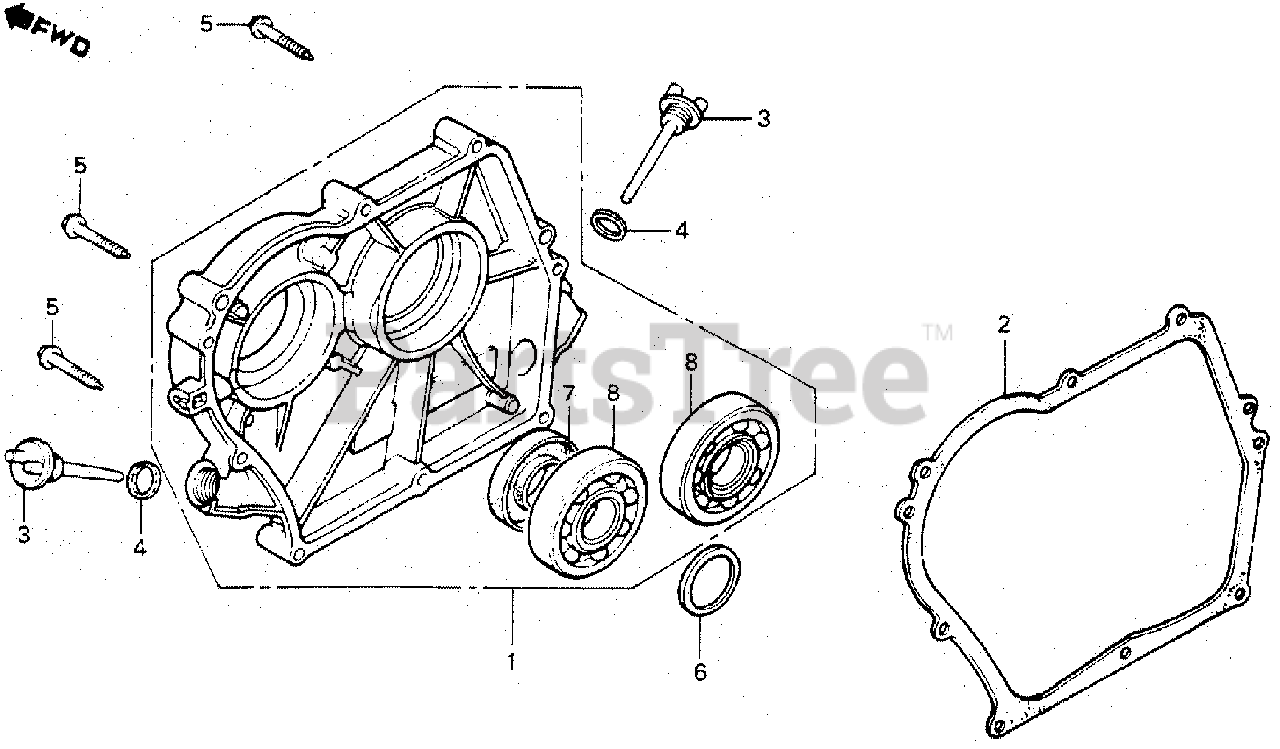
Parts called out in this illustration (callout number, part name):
1	COVER ASSY., CRANKCASE (L-TYPE)
2	GASKET, COVER
4	GASKET, OIL FILLER CAP
5	BOLT, FLANGE (6X32)
6	WASHER, THRUST SPRING
7	OIL SEAL (25X41X6)
8	BEARING, RADIAL BALL (6205)
